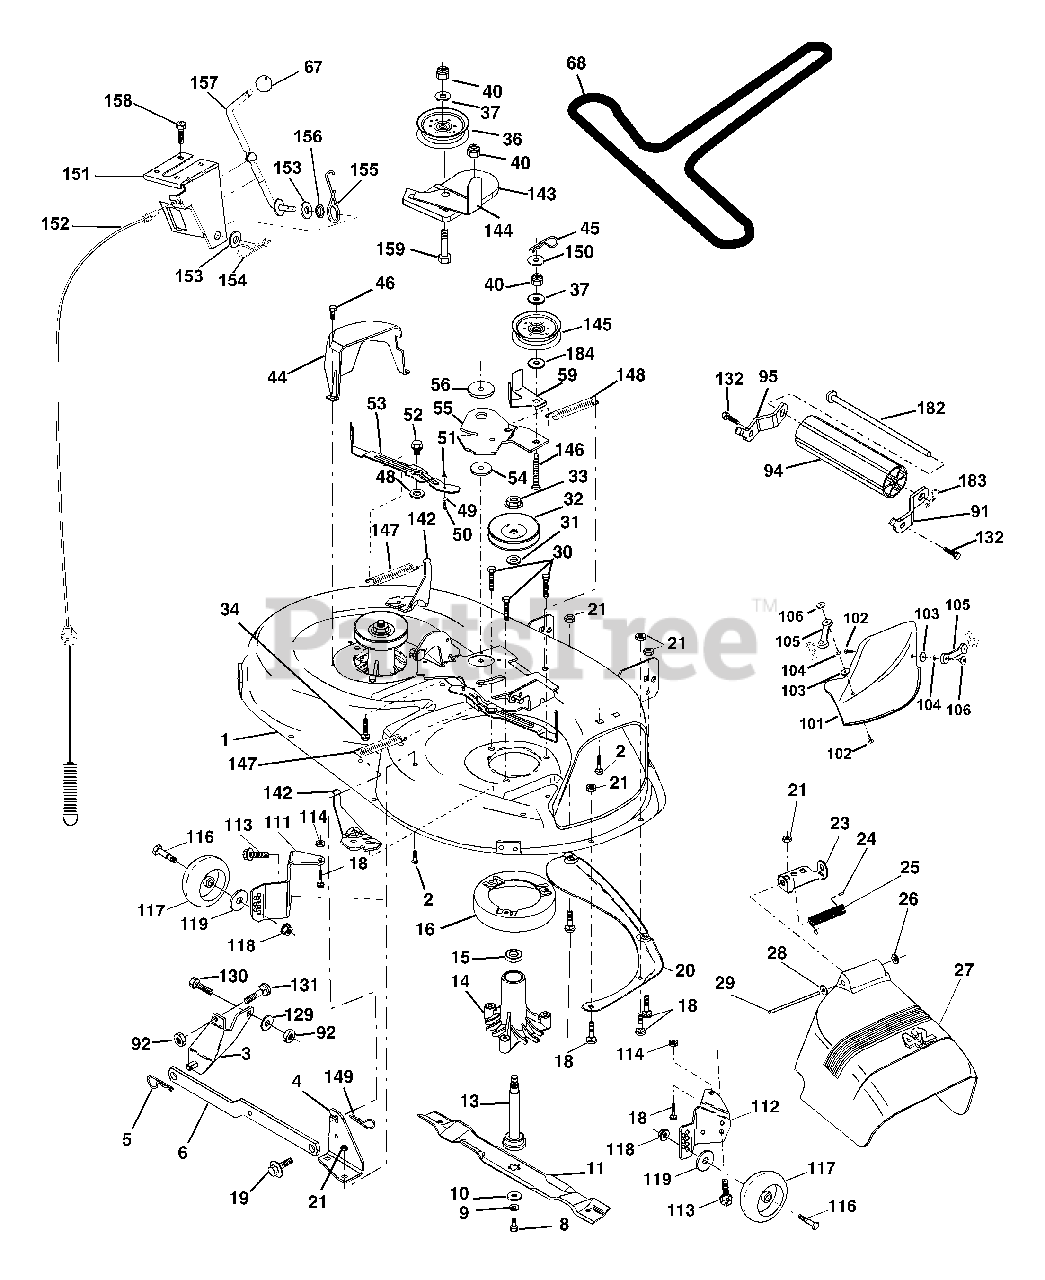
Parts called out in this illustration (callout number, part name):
1	Deck Asm MWR 42"weldment
2	Bolt Rdhd Sqnk 5/16-18unc X3/4
3	Bracket Asm Fr Sway Bar 38/42
4	Bracket Asm Deck 42"sway Bar
5	Retainer Spring
6	Deck Sway Bar
8	Bolt 3/8 - 24 X 1.25 Gr 8
9	Washer Lock Hvy 3/8
10	Washer Hard Blade Mower Vented
11	Blade, 42" Mulching Std
11	Blade, 42" Mulching Premium
11	Blade, 42" Hi-Lift
13	Shaft Asm W/lower Bearing
14	Housing Mandrel Vented
15	Bearing Ball Mandrel
16	Stripper Mower
18	Bolt Rdhd Sqnk 5/16-18 X 5/8
19	Bolt Shoulder
20	Baffle Vortex 42
21	Nut Crownlock 5/16-18 UNC
23	Bracket Deflector Mower 42"
24	Cap Sleeve 80x 112 Blk Mower
25	Spring Torsion Deflector 2 52
26	Nut Push Phos & Oil
27	Shield Deflector Mower 42" Blk
28	Washer 11/32 X 5/8 X 16 Ga
29	Rod Hinge 42"6 75 Wlg
30	Screw Thd Rolling
31	Washer Spacer Mower Vented
32	Pulley Mandrel 42"
33	Nut Toplock Flng
34	Bolt Rdhd 3/8-16uncx1-3/4 Gr5
36	Pulley Idler Flat 3 060
37	Washer 13/32 X 13/16 X 16
40	Nut Crownlock 3/8-16 UNC
44	Guard Mandrel LH Black
45	Spring Retainer 1" Zinc/cad
46	Screw Hex Thd Cut 1/4-20 x 5/8 T
48	Washer Hardened Smaller
49	Roller Asm Cam Follower 42"dec
50	Bolt Shldr 10-24 Zinc Gr 5 42"
51	Nut Lock #10-24 Unc
52	Bolt Shoulder 5/16-18 Unc Blkz
53	Arm Asm Pad Brake
54	Washer Hardened
55	Arm Idler 42"mower LT/YT
56	Spacer Retainer Mower
59	Guard TUV Idler
67	Knob Rd 3/8-16 Plstc Thds Blk
68	V-Belt Mower 42"
91	Bracket Roller Nose LH
92	Nut Lock Hex w/Ins. 3/8-16 Unc
94	Roller Nose
95	Bracket Roller Nose RH
101	Cover Mulch 42"
102	Screw Pan Head Phillip 10-24 x 5/8
103	Washer #10
104	Washer Lock #10
105	Latch Asm. Mulch
106	Nut Weld #10-24
111	Bracket Wheel Gauge LH 42" Deck
112	Bracket Gauge Wheel RH 42" Deck
113	Screw Tapping 3/8-16 x .625
114	Nut Keps 5/16-18 Unc
116	Bolt Shoulder
117	Wheel Gauge
118	Nut Centerlock 3/8-16 UNC
119	Washer 3/8 x 7/8 x 14 Ga.
129	Washer 13/32 x 13/16 x 12 Ga.
130	Bolt Rd Hd Sqnk 3/8-16 Unc x 1
131	Bolt Fin Hex 3/8-16 Unc x 1 Gr. 5
132	Screw Hex Wsh Thdr. 3/8-16 x 3/4
142	Arm Spring Brake Mower
143	Bracket Arm Idler 42"
144	Keeper Belt 42" Clutch
145	Pulley Idler Flat
146	Bolt Carriage Idler
147	Spring Extension
148	Spring Return Idler
149	Retainer Spring Yellow
150	Washer 9/32 x 3/4 x 16 Ga.
151	Bracket Clutch Cable
152	Clutch Cable 42"
153	Washer Flat 3/8" Type B
154	Spring Retainer
155	Spring Retention Lvr Cltch Cab
156	Spacer Clutch Cable
157	Rod Clutch Cable 3/8"
158	Screw Hex Thd Cut 1/4-20 x 1/2
159	Bolt Rdhd Sqn 3/8-16 Unc x 1-3/4
182	Rod Roller Nose
183	Retainer Spring
184	Washer 13/32 x 7/8 x 10 Ga.
